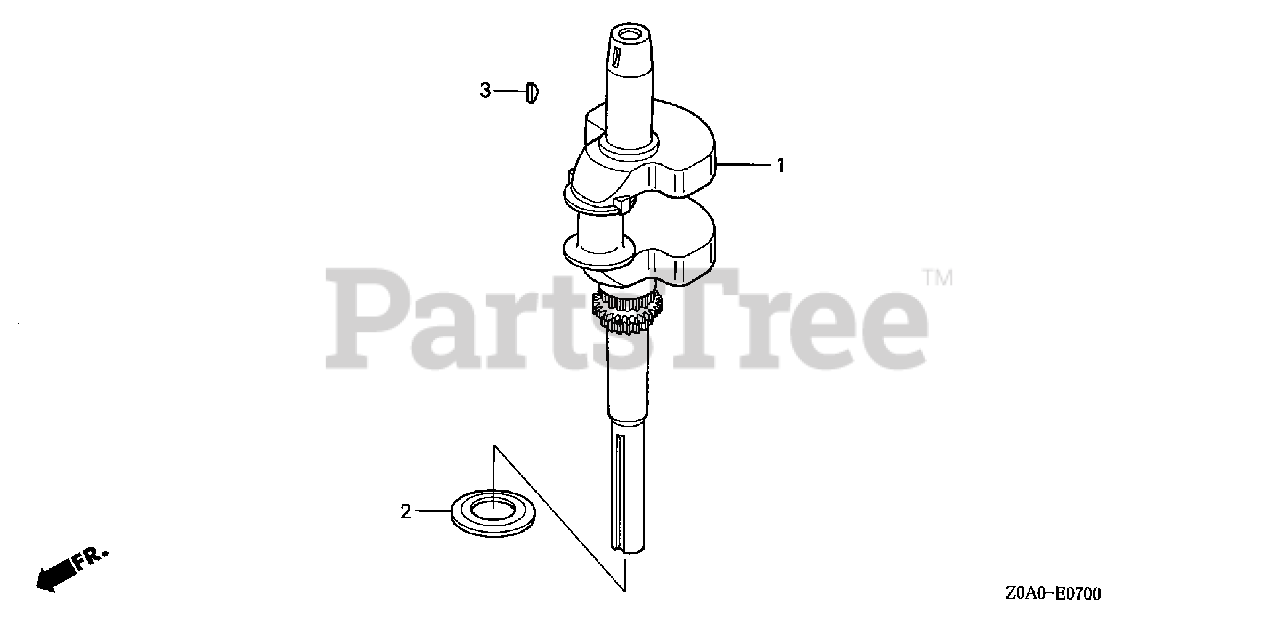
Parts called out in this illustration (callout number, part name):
1	CRANKSHAFT
2	WASHER, THRUST
3	KEY, SPECIAL WOODRUFF (25X18)
